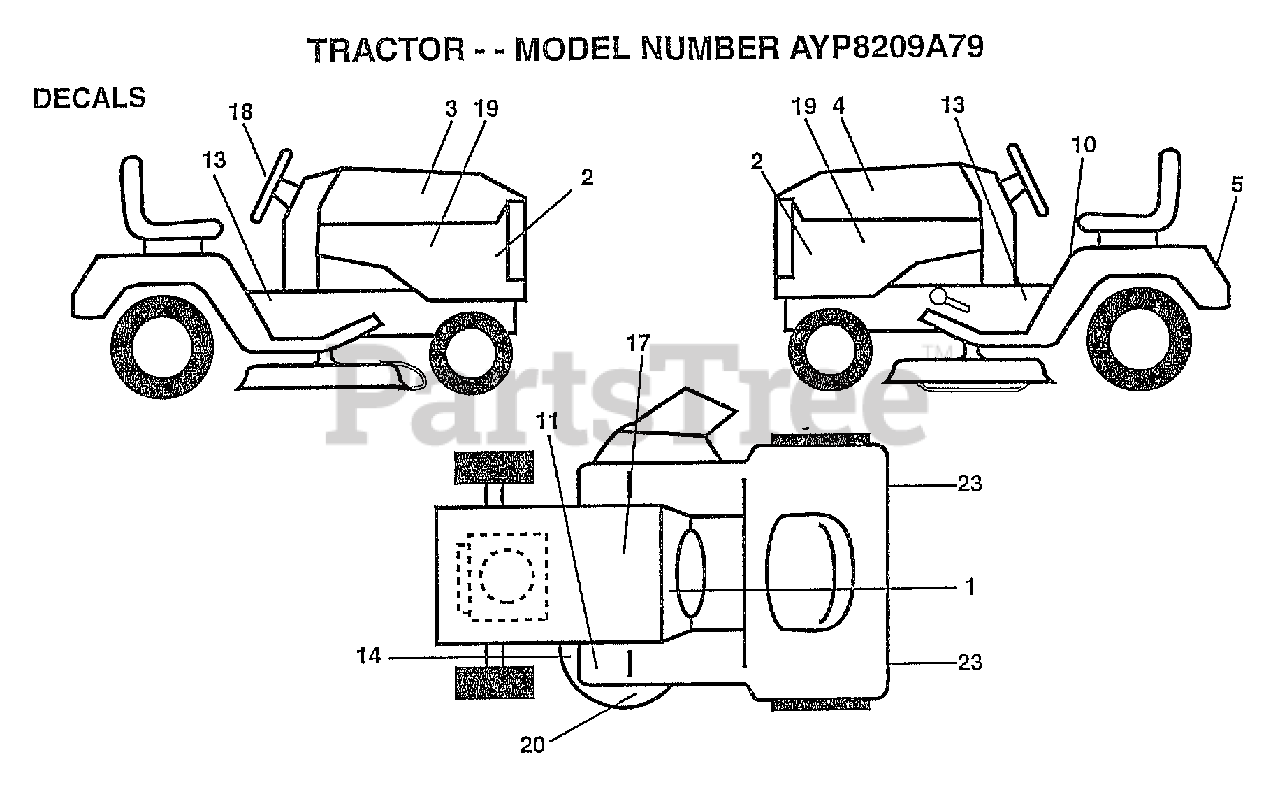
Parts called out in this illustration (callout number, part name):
1	"DECAL-OPER,GEAR D"
2	NAMEPLATE.HD.WIZA
3	DECAL.HD.RH.WIZRD
4	DECAL.HD.LH.WIZRD
6	DECAL.GRILLE.WIZ+
10	"DECAL DANGER,FEND"
13	"DCL.CHASSIS.50"""
14	"DECAL.V.BELT.44"""
17	DECAL.BATRY.3-3908
18	DECAL INS STG WHL
19	"DECAL,PNL SIDE BS"
20	DECAL DECK WIZ +
23	REFLECTOR-TAIL YT
